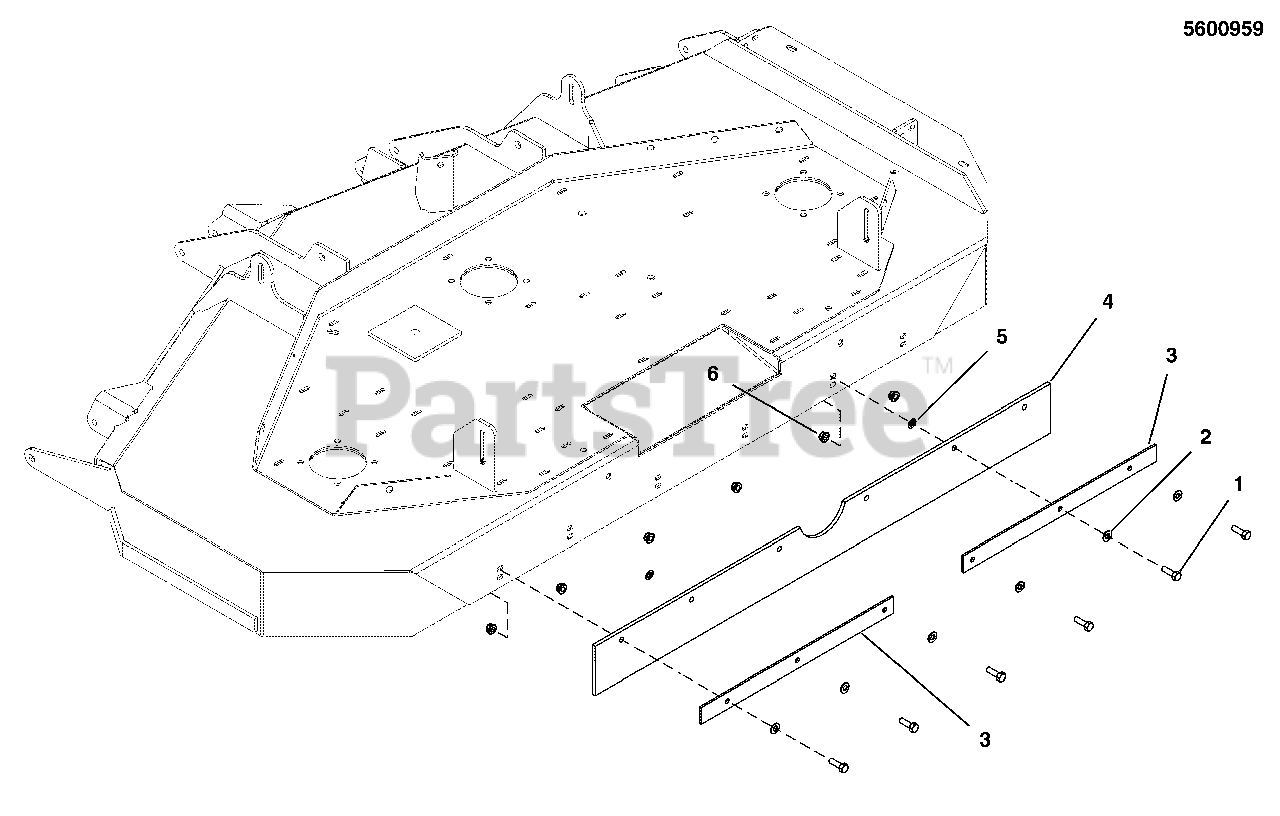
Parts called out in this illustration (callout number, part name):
1	BOLT, 5/16-18 X 1 GD5 CZ
2	WASHER, 5/16" SAE
3	PLATE, SUPPORT, S800X - BLK
4	FLAP, STRIPER, 61 DECK
5	5/16 PUSH-ON NUT RETAINER, STL, CZ
6	NUT, 5/16-18 HEX NYLOCK FLANGE
